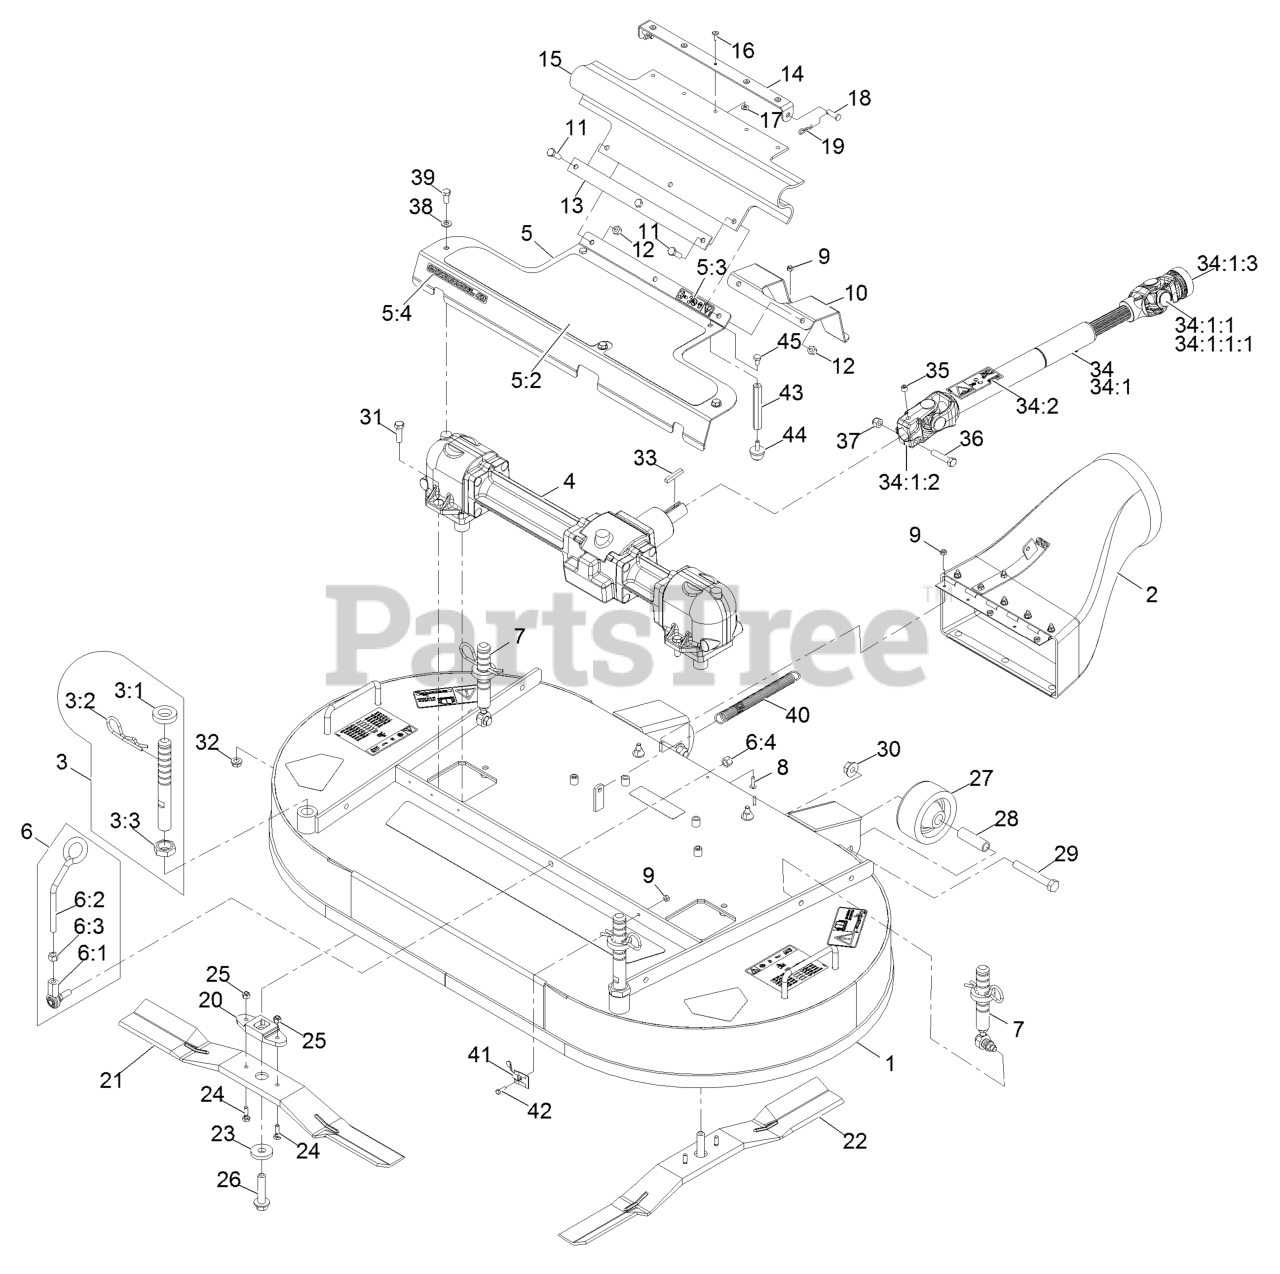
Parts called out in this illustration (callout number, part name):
1	DECK DECAL AND BAFFLE ASM
2	DISCHARGE TUBE ASM
3	FRONT DECK HEIGHT ADJUST
3:1	SPACER-DECK SUPPORT
3:2	PIN-CUT HEIGHT
3:3	NUT-JAM
4	GEAR BOX ASM
5	ASM,GEARBOX COVER 48 W/DE
5:2	PAD-ANTI SKID
5:3	DECAL-DANGER
5:4	Decal-Commercial 48
6	DECK LATCH ASM
6:1	BALLJOINT-RH
6:2	LATCH-DECK
6:3	NUT-HEX
6:4	NUT-LOCK
7	REAR DECK HEIGHT ADJUST A
8	SCREW-HEAD, TRUSS
9	NUT-LOCK, NI
10	GUARD-DRIVE SHAFT
11	SCREW-HH
12	NUT-LOCK, NI
13	STRAP-DRIVE, LINE COVER
14	BRACKET-GUARD, PTO
15	GUARD-PTO
16	RIVET-BLIND
17	WASHER-FLAT
18	PIN-CLEVIS
19	PIN-COTTER
20	DRIVER-BLADE
21	BLADE,25 INCH RH
22	BLADE,25 INCH LH
24	BOLT-SHEAR
25	NUT-LOCK, NI
26	BOLT-BLADE
27	ROLLER-DECK
28	SPACER-ROLLER
29	SCREW-HH
30	NUT-HHF
31	SCREW-HH
32	NUT-HHF, WHIZ
33	KEY-SQUARE
34	DRIVE SHAFT ASM
34:1	Drive Shaft-Telescoping
34:1:1	U-JOINT KIT
34:1:1:	FITTING-GREASE
34:1:2	YOKE-KEYED
34:1:3	YOKE-QUICK DISCONNECT
34:2	DECAL-DANGER, DRIVELINE
35	SCREW-SET, HSH
36	SCREW-HH
37	NUT-LOCK, NI
38	WASHER-PLAIN
39	SCREW-HH
40	SPRING-EXTENSION
41	CLIP-DECK, HOLD UP ROD
43	STAND-OFF
45	SCREW-HH
